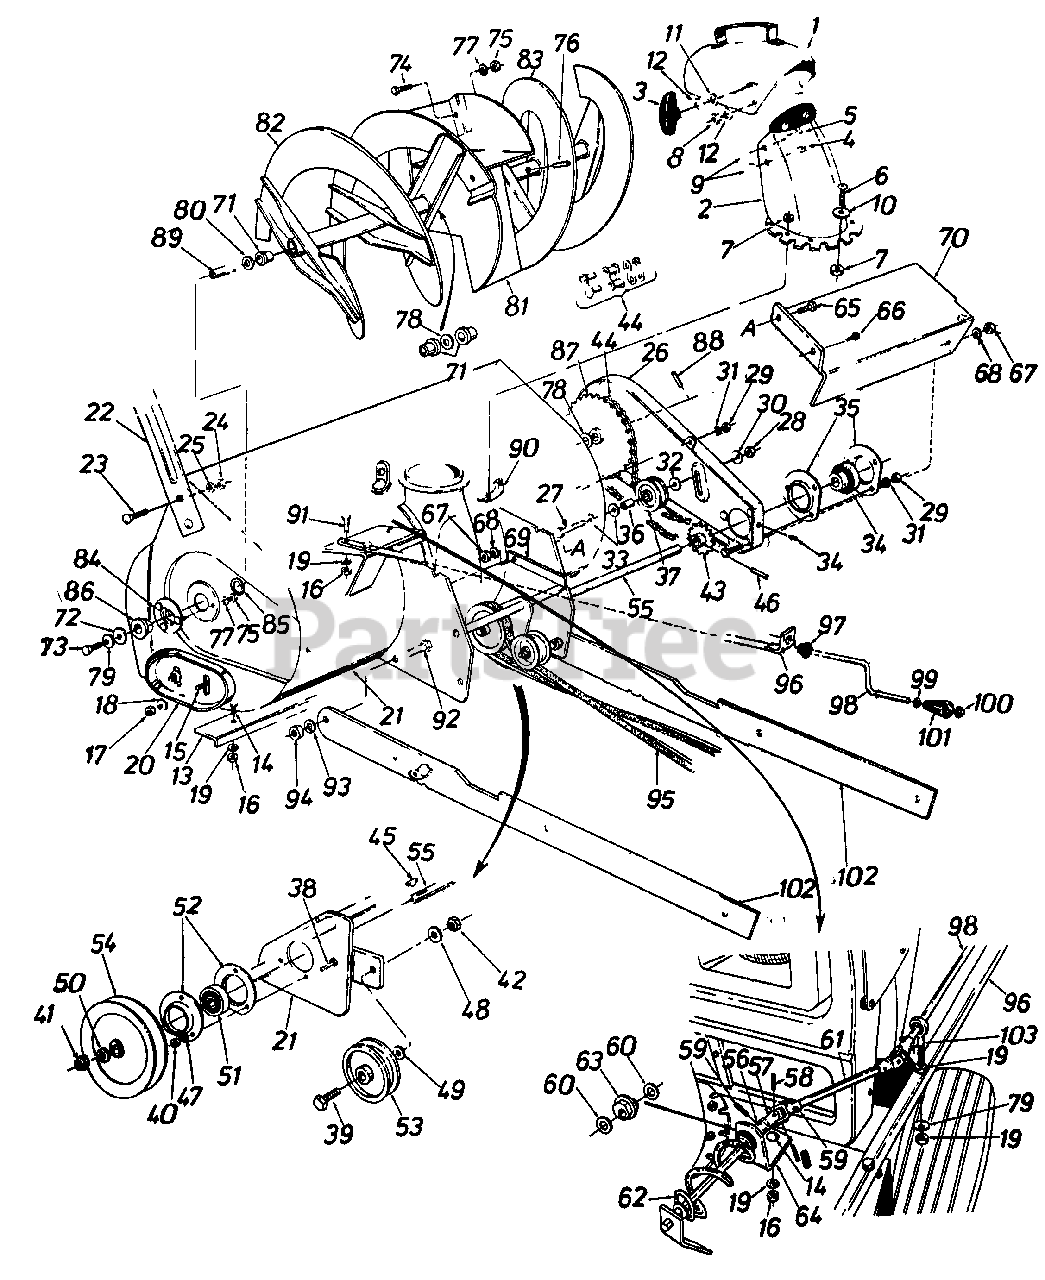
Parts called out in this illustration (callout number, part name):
1	Top Chute Ass'y.
2	Chute Ass'y. w/ Guard
3	Knob Handle Ass'y.
4	Carriage Bolt 5/16-18 x .62" Lg.*
5	Carriage Bolt 5/16-18 x 1.0" Lg.*
6	Truss Mach. Scr. 1/4-20 x .50" Lg.
7	Hex Cent. L.-Nut 1/4-20 Thd.
8	Hex Cent. L-Nut 5/16-18 Thd.
9	Fl.-Wash. .531" I.D. x 1.25" O.D.
10	Fl. Wash .285" 1 D. x 1.25" O.D.
11	Fl-Wash. .344" I.D. x I.D. x 1.125" O.D.
12	Bell.-Wash. .345" I.D. x .88" O.D.
14	Carriage Bolt 5/16-18 x .62" Lg.
15	Carriage Bolt 3/8-16 x .62" Lg.*
16	Hex Nut 5/16-18 Thd.
17	Hex Jam Nut 3/8-16 Thd.
18	Bell. Wash. .400" I.D. x .88" O.D.
19	L.-Wash. 5/16" I.D.'
20	Slide Shoe
21	Spiral Hsg. Ass'y.-36"
22	Guide Blade
23	Carriage Bolt 5/16-18 x .62" Lg.*
24	Hex Nut 5/16-18 Thd.
25	L.-Wash. 5/16" I.D.*
26	Chain Guard Ass'y.
27	Hex Bolt 3/8-16 x 2.00 Lg.
28	Hex Inst.-Nut 3/8-16 Thd.
29	Hex Nut 5/16-18 Thd.*
30	Bell.-Wash. .400" I.D. x .88 O.D.
31	L.-Wash. 5/16" I.D.*
32	Fl.-Wash. .406" I.D. x 1.25" O.D.
33	Fl.-Wash. .385" I.D. x .87" O.D.
34	Ball Brg...75" I.D.
35	Flangette
36	Spacer .375" I.D. x .60" O.D.
37	Fl.-ldler w/ Flanges 2.0" O.D. Plastic
38	Hex Sems Bolt 5/18 x .75" Lg.
39	Hex Bolt 3/8-16 x 1.75" Lg.*
40	Hex Nut 5/16-18 Thd.*
41	Hex Jam Nut 3/4-10 Thd.
42	Hex Jam Nut 3/8-16 Thd.
43	Sprocket Ass'y.-14 Teeth
44	#420 Chain x 1/2" Pitch- 0 78 Links
45	#61 Hi-Pro-Key 3/16 x 5/8" Dia.
46	Spring Pin Spir. 5/16" Dia. x 1.75" Lg.
47	L.-Wash. 5/16" I.D.*
48	L.-Wash. 3/8" I.D.*
49	Fl.-Wash. .406" I.D. x 1.25" O.D.
50	Spring L.-Wash. 3/4" I.D.
51	Self-Aligning Brg.
52	Flangette
53	Idler Pulley
54	5i8 V Pulley .75" I.D. x 6.0" O.D.
55	Drive Shaft Ass'y.
56	Joint Brkt. Ass'y.
58	Spring Pin Spir. 3/16 Dia. x 1.0" Lg.
59	Spirol Pin-1/8" Dia. x .812" Lg.
60	Fl.-Wash. .385" I.D. x .62" O.D.
61	Chute Crank Ext. Rod 3/8" Dia. x 6.0" Lg.
62	Chute Crank Ass'y. R.H. 6 1.'4" Lg.
63	Plastic Bushing 380" I.D.
64	Chute Crank Brkt.
65	Hex Bolt 1/4-20 x .62" Lg.
66	Hex Wash. S-Tap Scr. 1/4-20 x .50" Lg.
67	Hex Nut 1/4 20 Thd.*
68	L.-Wash. 1/4. .I.D.*
70	Drive Shaft Cover
71	Plastic Bushing
72	Washer .39" I.D. x 1.75" O.D.
73	Hex Bolt 5/16-18 x .88" Spec.
74	Carriage Bolt 5/16-18 x .75" Lg.*
75	Hex Nut 5/16-18 Thd.
76	Spring Pin Spir. 5/16" Dia. x 1.75" Lg.
77	L.-Wash. 5/16" I.D.*
78	Truss Wash 1.03" I.D. x 1.62" O.D.
79	Bell.-Wash. .345" I.D. x .88" O.D.
80	Fl.-Wash. 1.0" I.D. xl.75" O.D.
85	Snap Ring for 1.50" Shaft
86	Flange Brg. w/ flats 1.00" I.D.
87	Sprocket Hub Ass'y. 40 Teeth
88	Spring Pin Spir 5/16 Dia. x 1.75" Lg.
90	Chute Flange Keeper Ass'y.
91	Hex Bolt 5/16-18 x 1.5" Lg.*
92	Hex Bolt 1/2-13 x 1.25" Lg.*
93	L.-Wash. 1/2" I.D.*
94	Hex Nut 1/2"-13 Thd.*
95	"V"-Belt 1/2" "A" x 89.0" Lg.
98	Chute Crank .375" Dia. x 33.0" Lg.
99	Fl.-Wash..385" I.D. x .62" O.D.
100	Push Nut 3/8" Rod
101	Knob Black-3/8" Dia. Hole
102	Linkage Arm
103	Eye Bolt 5/16-18 x 3.0" Lg.
